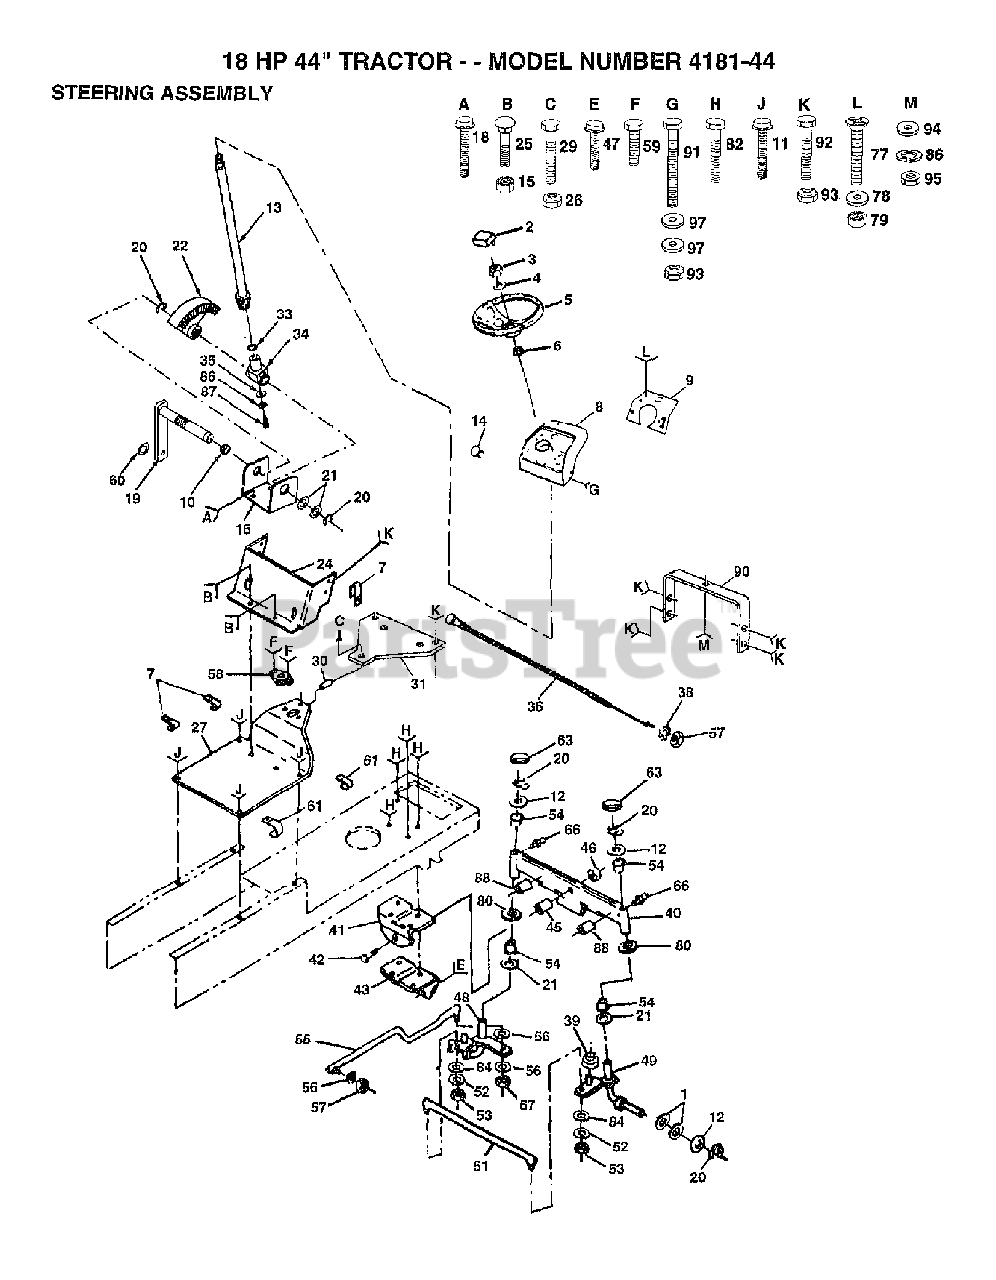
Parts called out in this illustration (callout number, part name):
2	INSERT STR WHL
3	NUT.HEX.1/2-20
5	Steering Wheel
7	CLIP T
10	NYLINER T (7283A)
13	SHAFT ASS'Y STEER
14	PLUG-DASH T
16	BRKT,STEERING
19	SHAFT,PITMAN
20	RING CLIP
21	WASHER THRUST
22	GEAR.SECTOR
24	DASH LOWER YT NLA
26	NUT.71038.31-18.HEX.NYLOCK
31	PLATE, BATTERY
33	THRUST WASHER
34	SHAFT,SUPPORT
35	WASHER
36	CONTROL CHOKE
38	LOCKWASHER
39	Poulan TBD
40	AXLE ASSY
41	SUPPORT-SADDLE LT NLA
43	SUP-SADDLE FRT LT
46	LOCK NUT
47	SCREW LT
52	LOCKWASHER
53	LOCKNUT
54	BEARING.STEERING.COLUMN
55	DRAG LINK
56	WASHER, LOCK 3/8
57	NUT
58	BUSHING
59	SCREW LT
60	WASHER
61	CLIP,INSULATOR
63	CAP.SPINDLE.BLACK
66	ZERK.GREASE.TAPERED
78	WASHER
84	WASHER M
86	LOCKWASHER
90	SUPPORT ASS'Y
93	NUT
94	WASHER PM
95	NUT
97	WASHER
